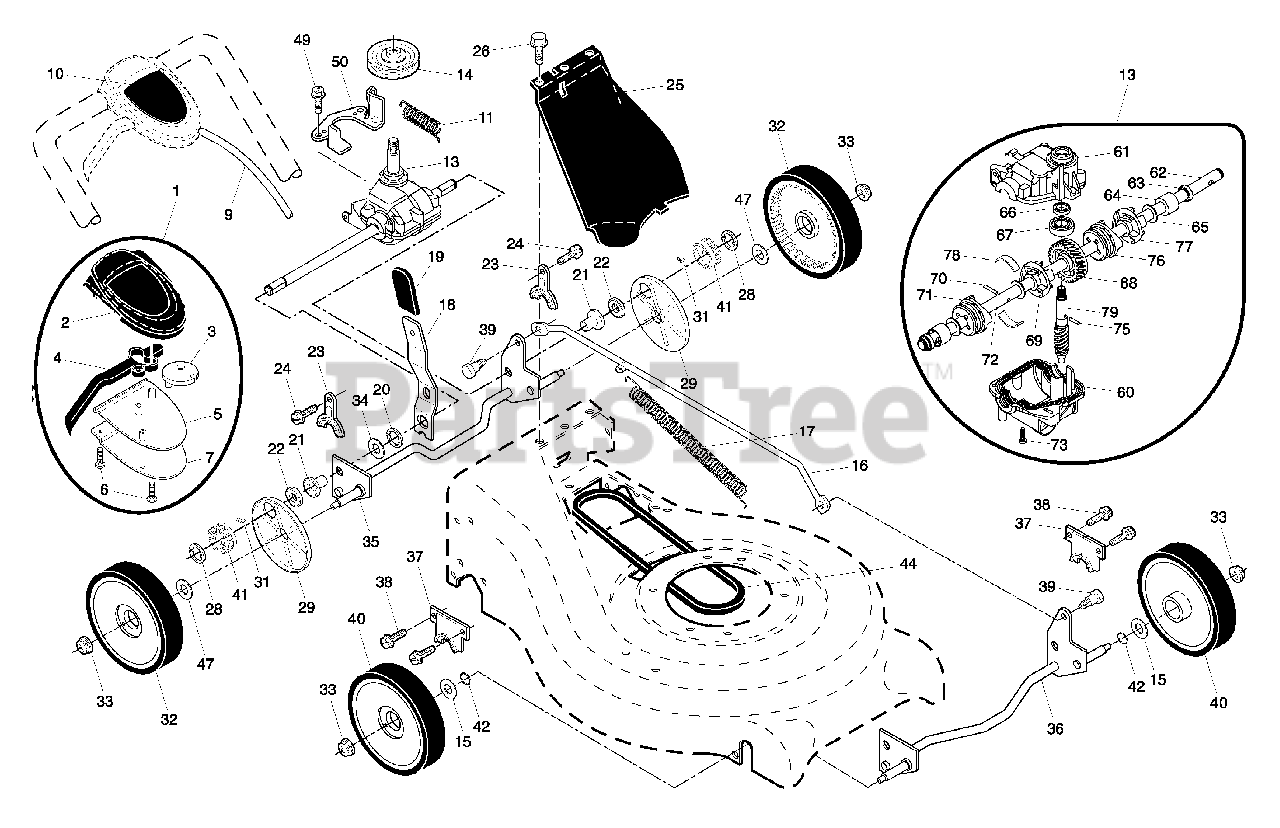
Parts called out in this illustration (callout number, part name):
1	Drive Control Assembly, Auto-Walk
2	Cover, Top, Auto-Walk Drive Control
4	Lever, Auto-Walk Drive Control
5	Cover, Bottom, Auto-Walk Drive Control
6	Screw, Phillips Head #10 x 5/8
7	Plate, Trigger, Auto-Walk Drive Control
9	Cable, Drive Control
10	Decal, Drive Control
11	Spring, Return
13	Gear Case Assembly
14	Pulley, Drive
15	Washer, Flat
16	Rod, Connecting
17	Spring, Extension
18	Spring Selector
19	Knob, Selector Spring
21	Bearing, Support
22	Bearing, Ball
23	Retainer, Drive Assembly, Stamped
24	Screw, Tapping, Hex Head 1/4-20 x 3/4
25	Cover Drive
26	Screw, Threaded, Rolled #10-25 x 1/2
28	E-Ring 7/16
29	Cover, Dust, Wheel
31	Seal, Friction
32	Wheel & Tire Assembly, Rear
33	Nut, Hex, Flangelock 3/8-16
35	Shaft Assembly, Rear
36	Shaft Assembly, Front
37	Retainer, Front Shaft
38	Screw #12 x 5/8
39	Bolt, Shoulder, Semi-Gimlet Point
40	Wheel & Tire Assembly, Front 8 x 2
47	Washer 1/2 x 1-1/2 x .134
49	Screw, Hi-Lo Thread
50	Belt Keeper
60	Case, Upper
61	Shaft, Output, Long
62	Seal, Output Shaft
65	Seal, Worm Shaft
66	Bearing, Ball
67	Gear, 28 Teeth
68	Fixed Dog Clutch, LH
69	Pin, Output Shaft
70	Movable Dog Clutch, LH
71	Shaft, Output, Short
72	Screw, Case
73	Case, Lower
75	Pin, Worm Shaft
76	Fixed Dog Clutch, RH
77	Movable Dog Clutch, RH
78	Spring, Leaf
79	Shaft, Worm
